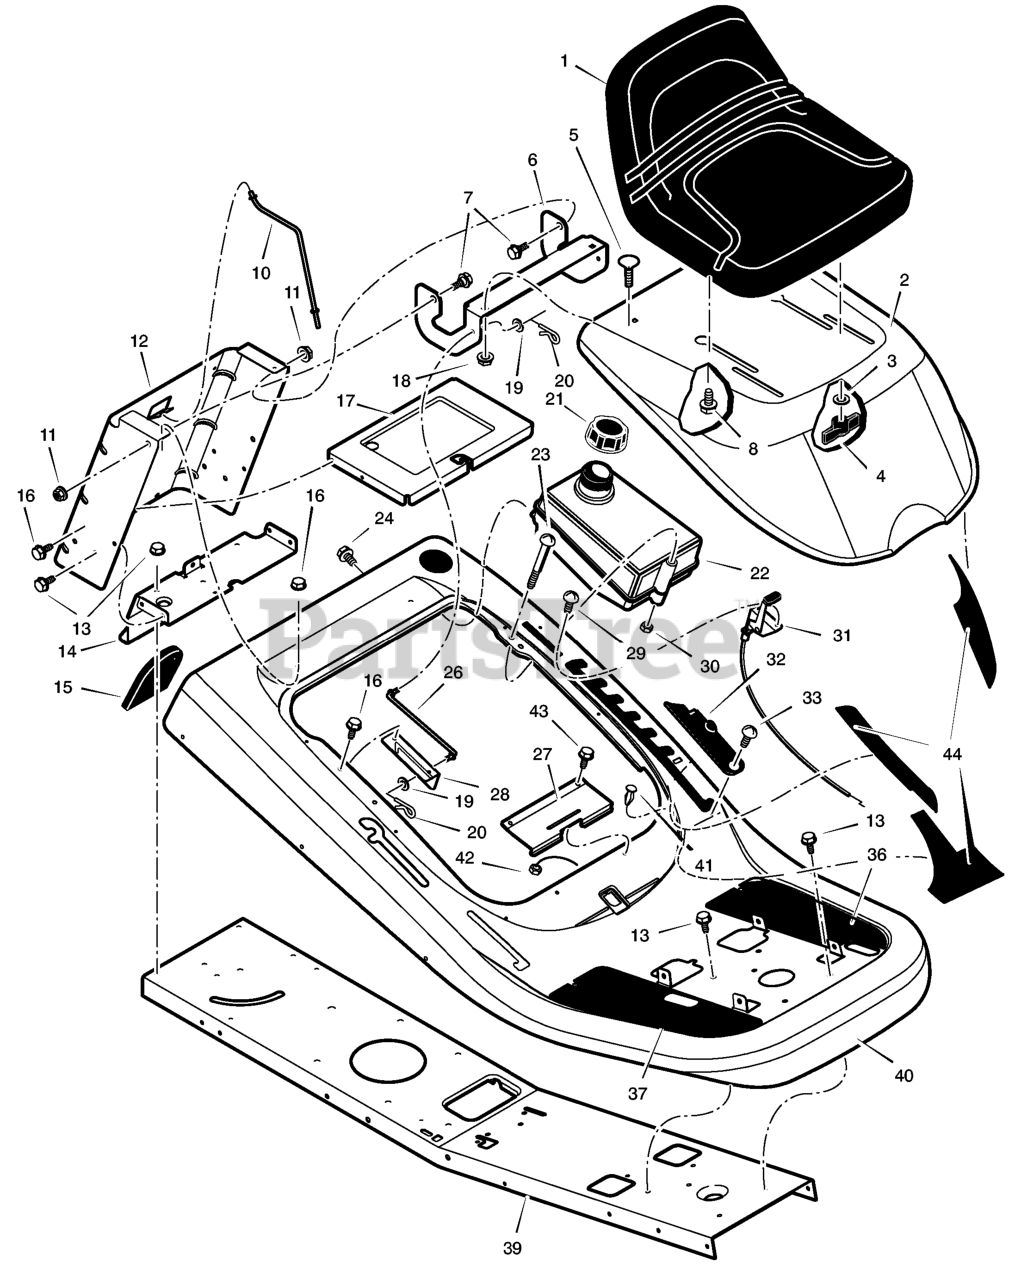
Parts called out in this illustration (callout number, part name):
1	Seat
3	Washer
4	Bolt, Wing
5	Bolt, Carriage
6	Bracket, Hinge
7	Bolt, Shoulder
8	Bolt, Shoulder
10	Rod, Battery
11	Nut, Flange
12	Plate, Rear
14	Plate, Hitch
17	TRAY, Battery
18	Nut, Flange
19	Washer
20	Pin, Cotter
21	Cap, Fuel Tank
22	Tank, Fuel
26	Rod, Hood Prop
27	Spring, Seat Deck
28	Bracket, Prop Rod
30	Nut, NY-Lock
31	Control, Throttle
32	Cover, Detent (Black)
33	Bolt, Shoulder
36	Footmat, Left
37	Footmat, Right
41	Bumper
42	Nut
43	Screw
44	Kit, Foil Heat Shield
47	Fastener, Panel
